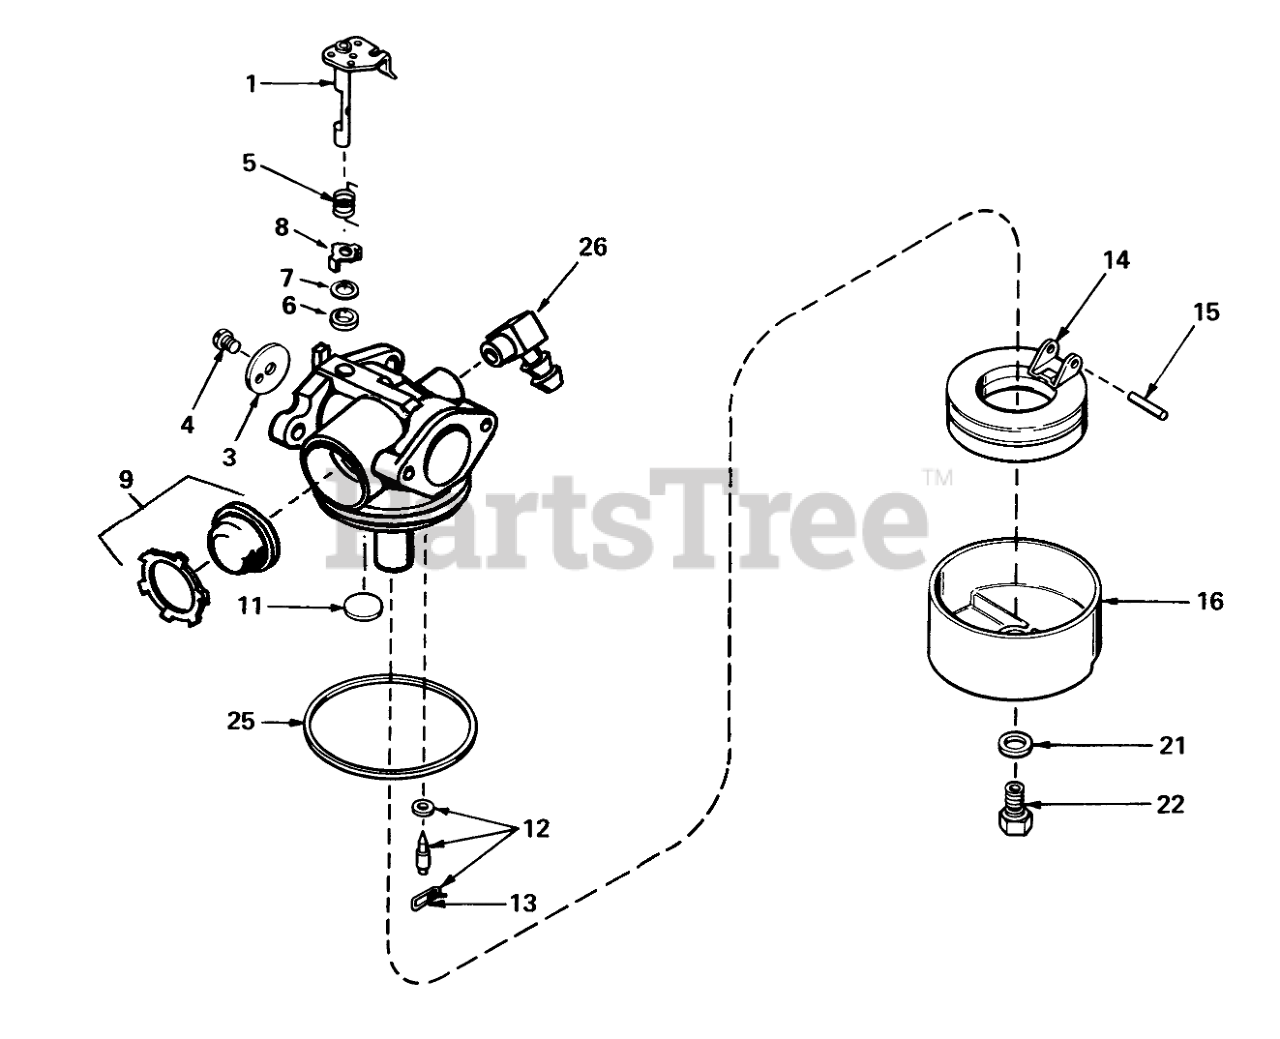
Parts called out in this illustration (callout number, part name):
1	Throttle Shaft and Lever ASM
3	Throttle-Shutter
4	Screw-Shutter
5	Spring, Return
6	Seal-Dust
7	Washer-Seal, Dust
8	Retainer, Seal
9	Primer Assy.
11	Plug-Welch, Atmospheric Vent
12	Inlet Needle, Seat & Clip Assy. (Incl. Ref. #13)
13	Clip-Spring
14	Float
15	Shaft-Float
16	Bowl Float
21	Gasket-Bowl
22	Nut-Float Bowl
25	O Ring-Bowl, Float
26	Fitting-Fuel
